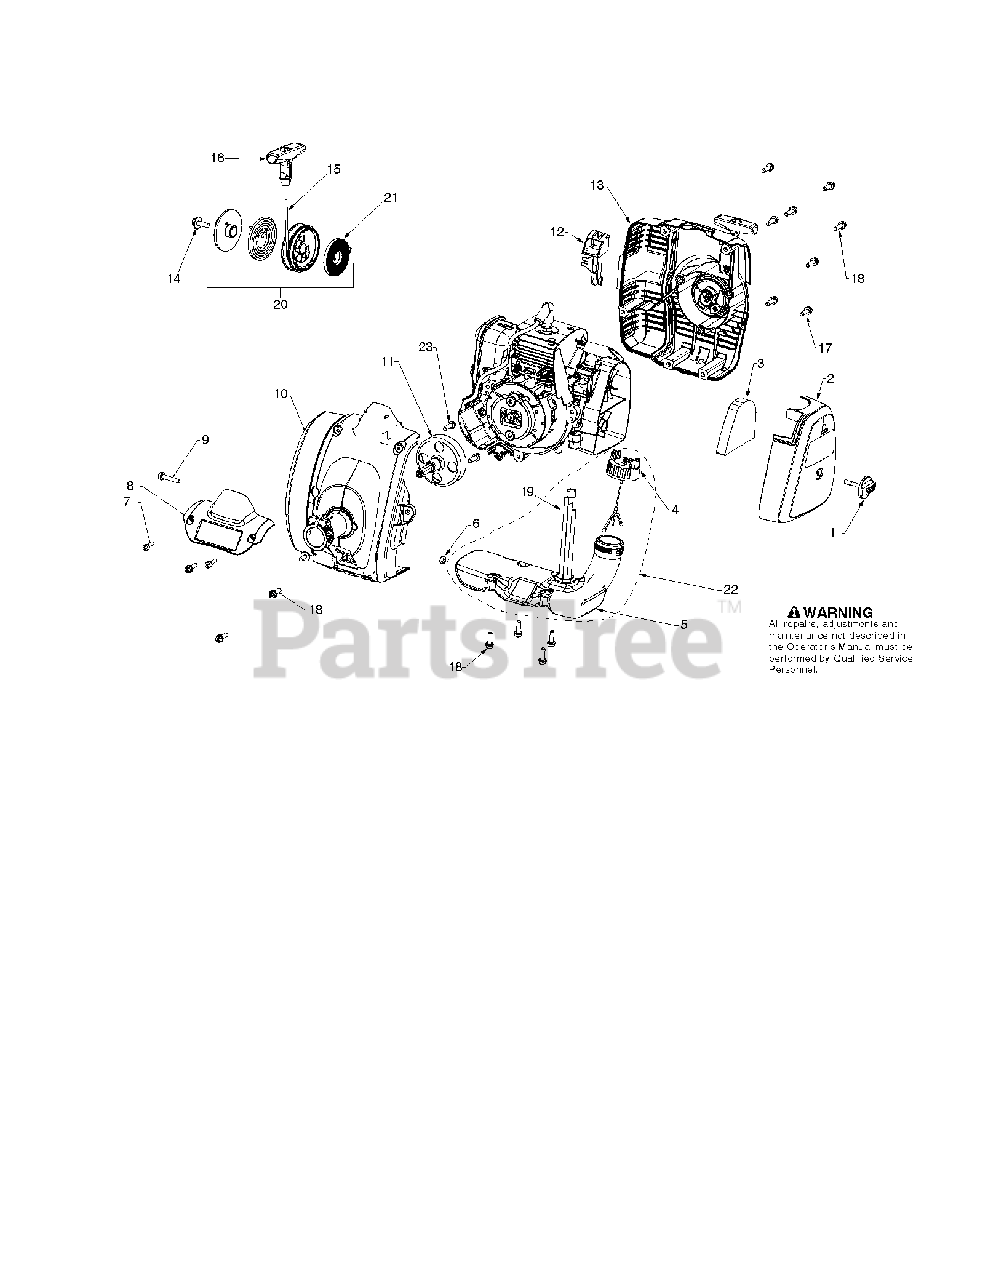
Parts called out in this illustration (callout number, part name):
6	NUT
12	CHOKE BUTTON
13	Starter Cover Assembly
19	Fuel Line Kit
20	Starter Pulley Kit
21	KIT STARTER SPRING
22	KIT FUEL TANK
